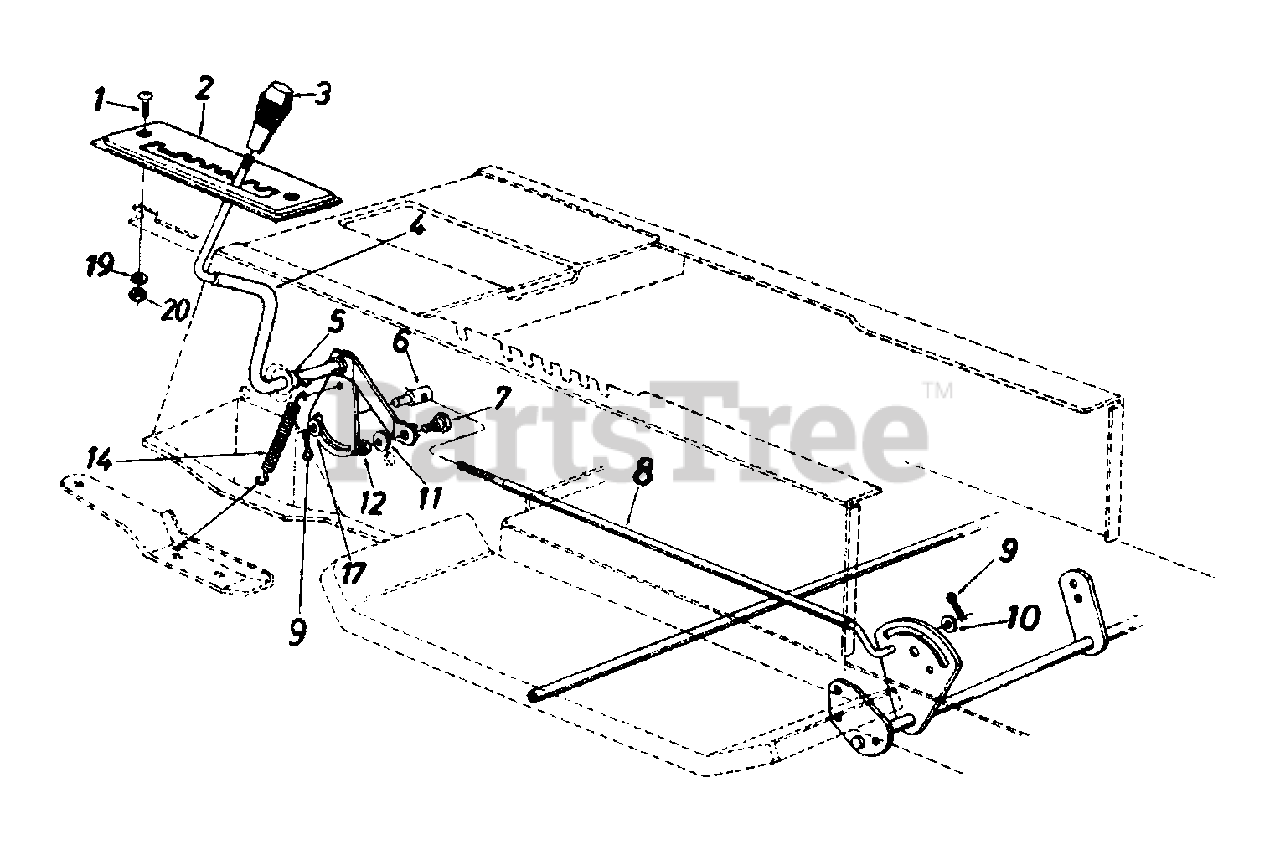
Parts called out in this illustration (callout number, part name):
1	Truss Mach. Scr. 1 4-20 x .75 Lg.
4	Speed Selector Lever Ass'y.
5	Flat Washer .53" I.D. x .93"
6	Ferrule 3/8-24 x .37" Dia.
7	Shoulder Bolt
8	Speed Control Link
9	Cotter Pin 3/32" Dia. x 1.0"
10	Fl-Wash..469" I.D. x .88"
11	L-Wash. 5/16" I.D.
12	Hex Nut 5/16-18 Thd. (Gr. 5)
14	Spring .38" O.D. x 3.18" Lg.
17	Fl-Wash..385" I.D. x 7/8"
19	L-Wash. 1/4" I.D.
20	Hex Nut 1/4-20 Thd. (Gr. 5)
